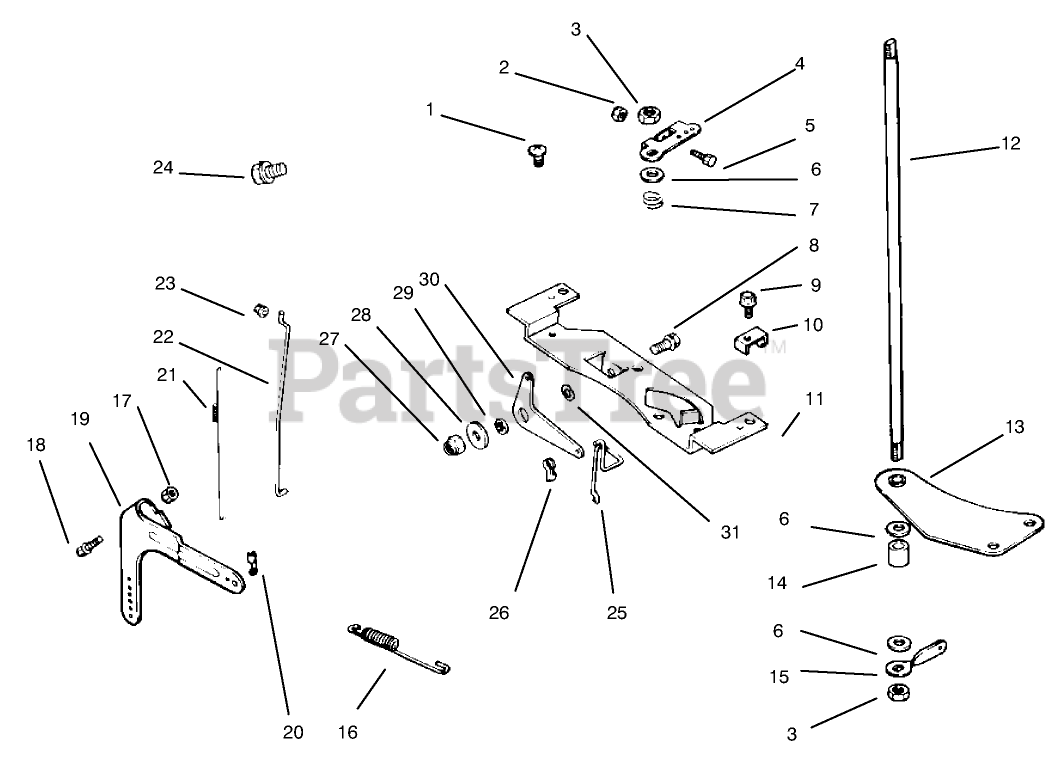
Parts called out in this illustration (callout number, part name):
1	Screw
2	Nut
3	Nut
4	Lever-Throttle Control
5	Screw
6	Washer
7	Spring-Throttle Shaft
8	Screw
9	Screw
10	Clamp
11	Bracket-Control
12	Shaft-Throttle
13	Bracket-Throttle Shaft
14	Spacer
15	Lever-Throttle Control
16	Spring-Governor
17	Nut
18	Screw
19	Lever-Govenor
20	Bushing-Linkage
21	Spring-Linkage
22	Linkage-Throttle
23	Bushing-Linkage
24	Screw
25	Linkage-Choke
26	Bushing-Linkage
27	Nut
28	Washer
29	Spacer
30	Lever-Choke
31	Washer
